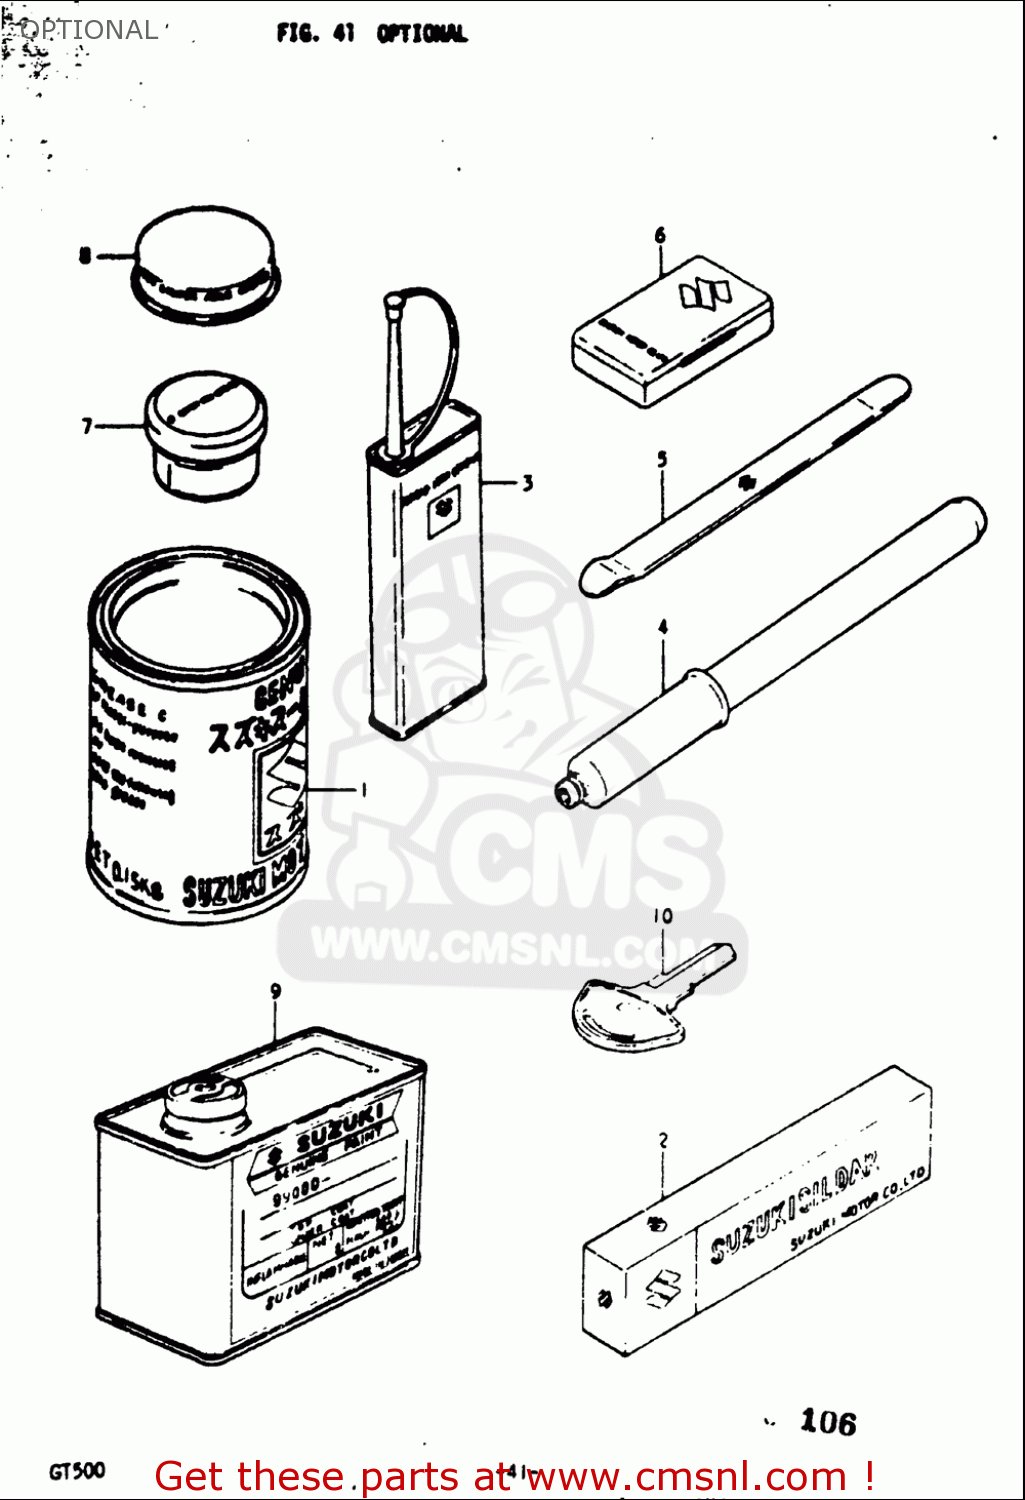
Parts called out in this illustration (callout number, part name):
1	GREASE(C)EP2 LITHIUM 150G
3	THREAD LOCK NO.1401 CLEAR 200G
5	LEVER,TIRE
7	GREASE,SILICON 20G
8	GREASE,PBC FOR BRK PAD 20G
10	KEY,BLANK
